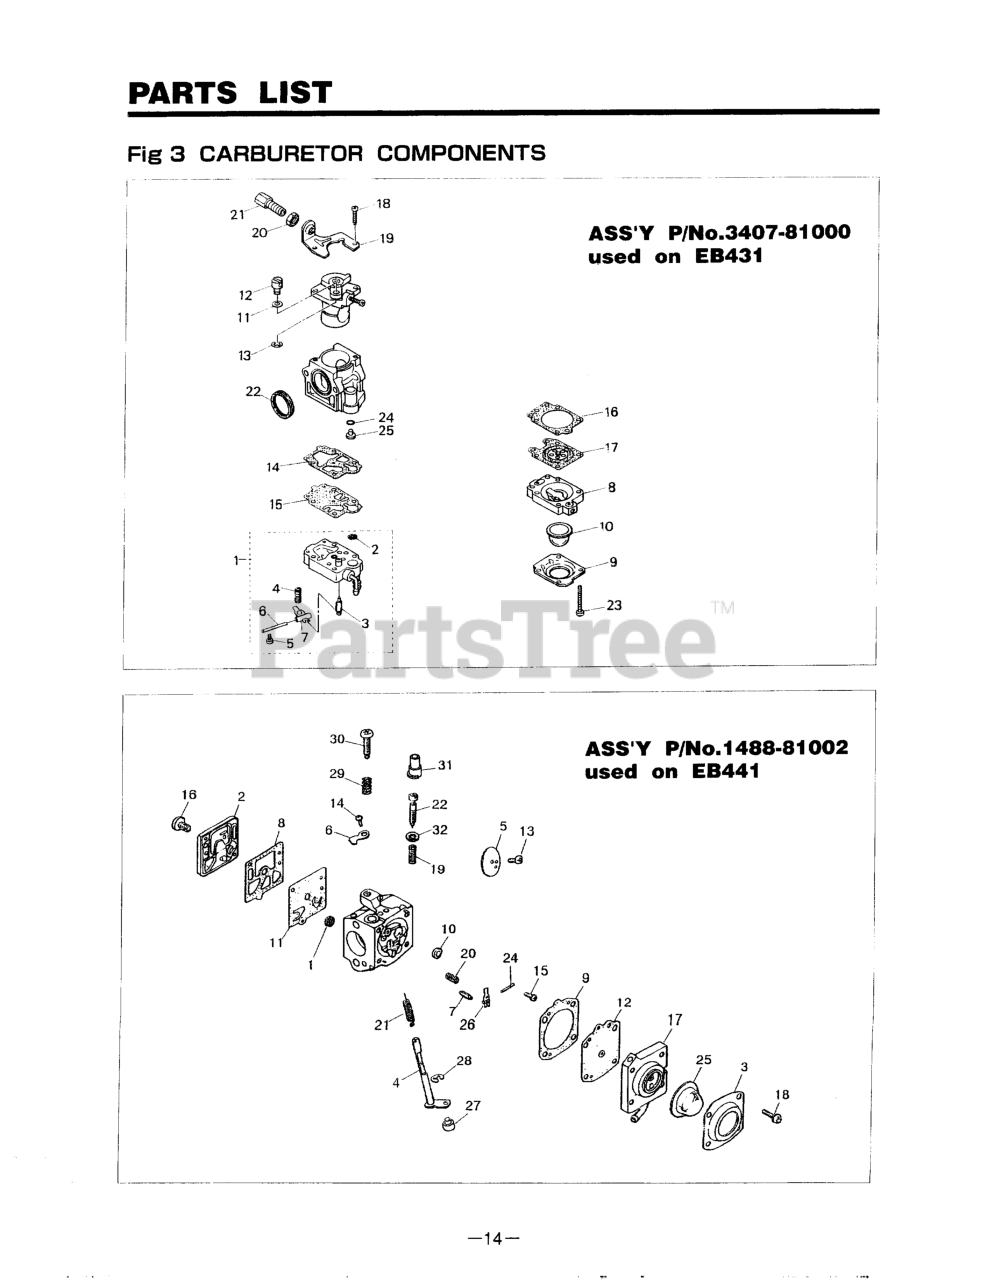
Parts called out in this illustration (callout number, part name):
2	COVER, PUMP
3	COVER, PUMP
4	SHAFT ASSEMBLY
5	VALVE, THROTTLE
6	THROTTLE STOP
7	VALVE, INLET
8	KIT ONLY
9	KIT ONLY
10	PLUG, WELSH
11	KIT ONLY
16	SCREW (RPLS 1491-81130)
17	BODY ASSY (RPLS 1491-81490)
18	SCREW (REPLACES 1491-81350)
20	KIT ONLY
21	SPRING
22	NEEDLE (NLA)
24	PIN, METERING LEVER
25	PUMP, PRIMER
26	KIT ONLY
27	SWIVEL (USE -06040)
29	SPRING, IDLE
NI	REBUILD KIT, EB430/440
NI	EB430/40 DIA/GASK KIT
